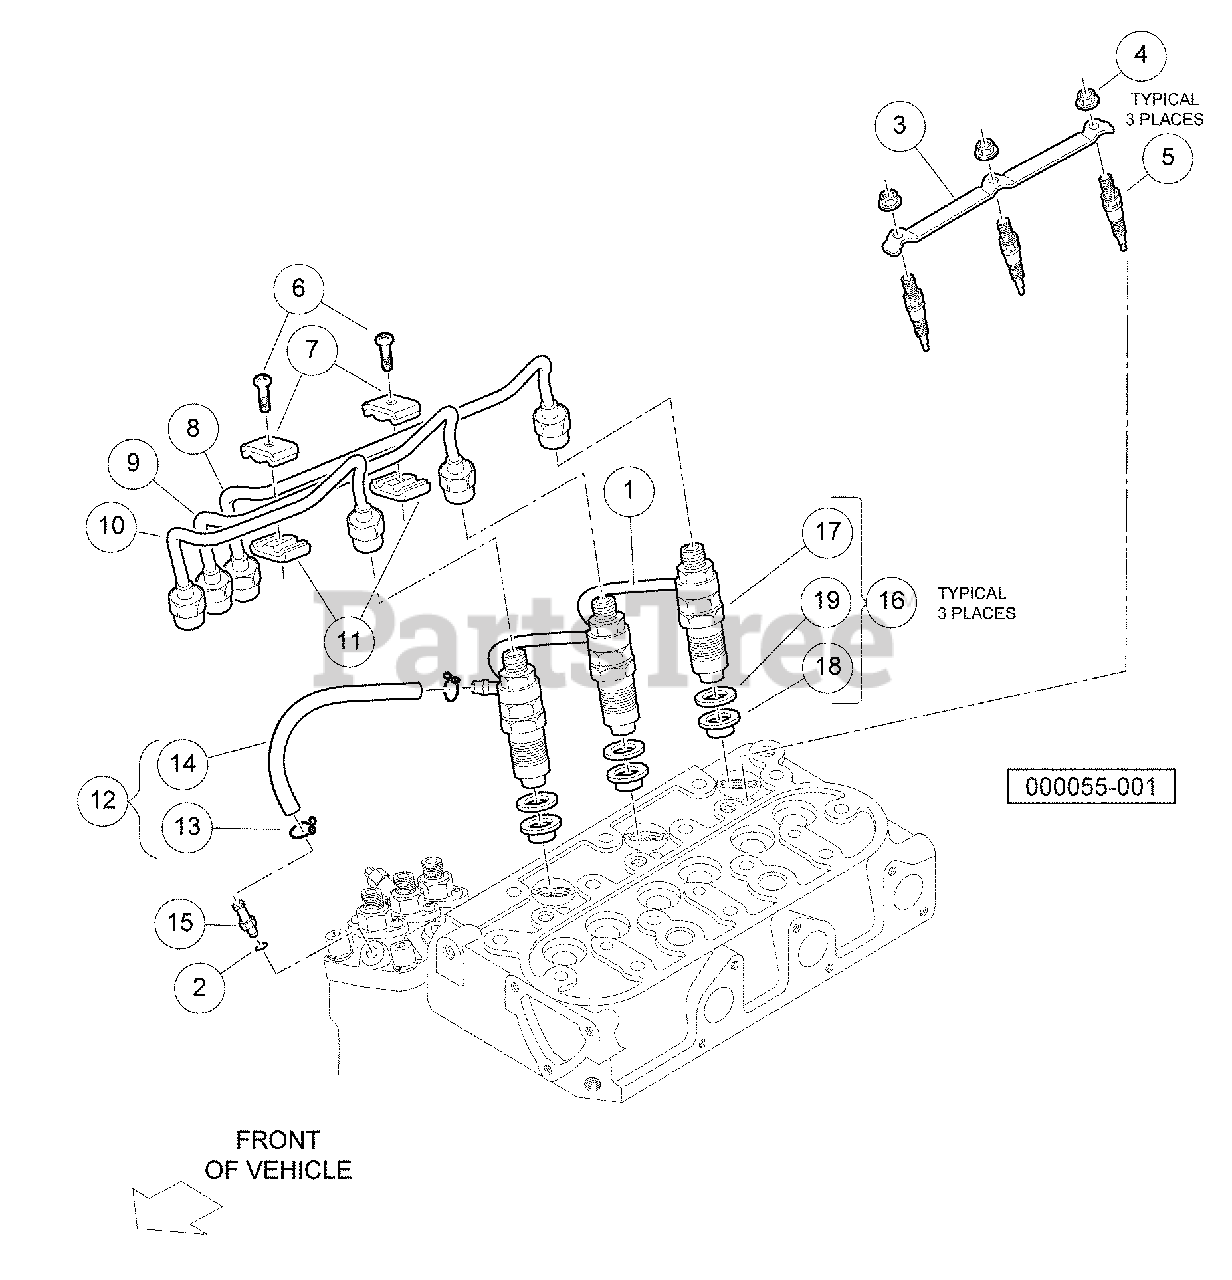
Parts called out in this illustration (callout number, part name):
1	Assy Pipe, D722 Fuel Over Flow
2	Gasket, 6 X 10
3	Cord, Glow Plug
4	Nut, Flange,m4
6	Screw, Washer
7	Clamp, Pipe, Top
8	Pipe, Injection, Left
9	Pipe, Injection, Right
10	Pipe, Injection, Middle
11	Clamp, Pipe, Bottom
12	Assy Pipe, Over Flow
13	Clip, Pipe, Return
14	Hose, Overflow
15	Screw, Air Bleeder
16	Kit, Holder, Nozzle
17	Assembly, Nozzle Holder
18	Seal, Heat
19	Gasket, Nozzle
